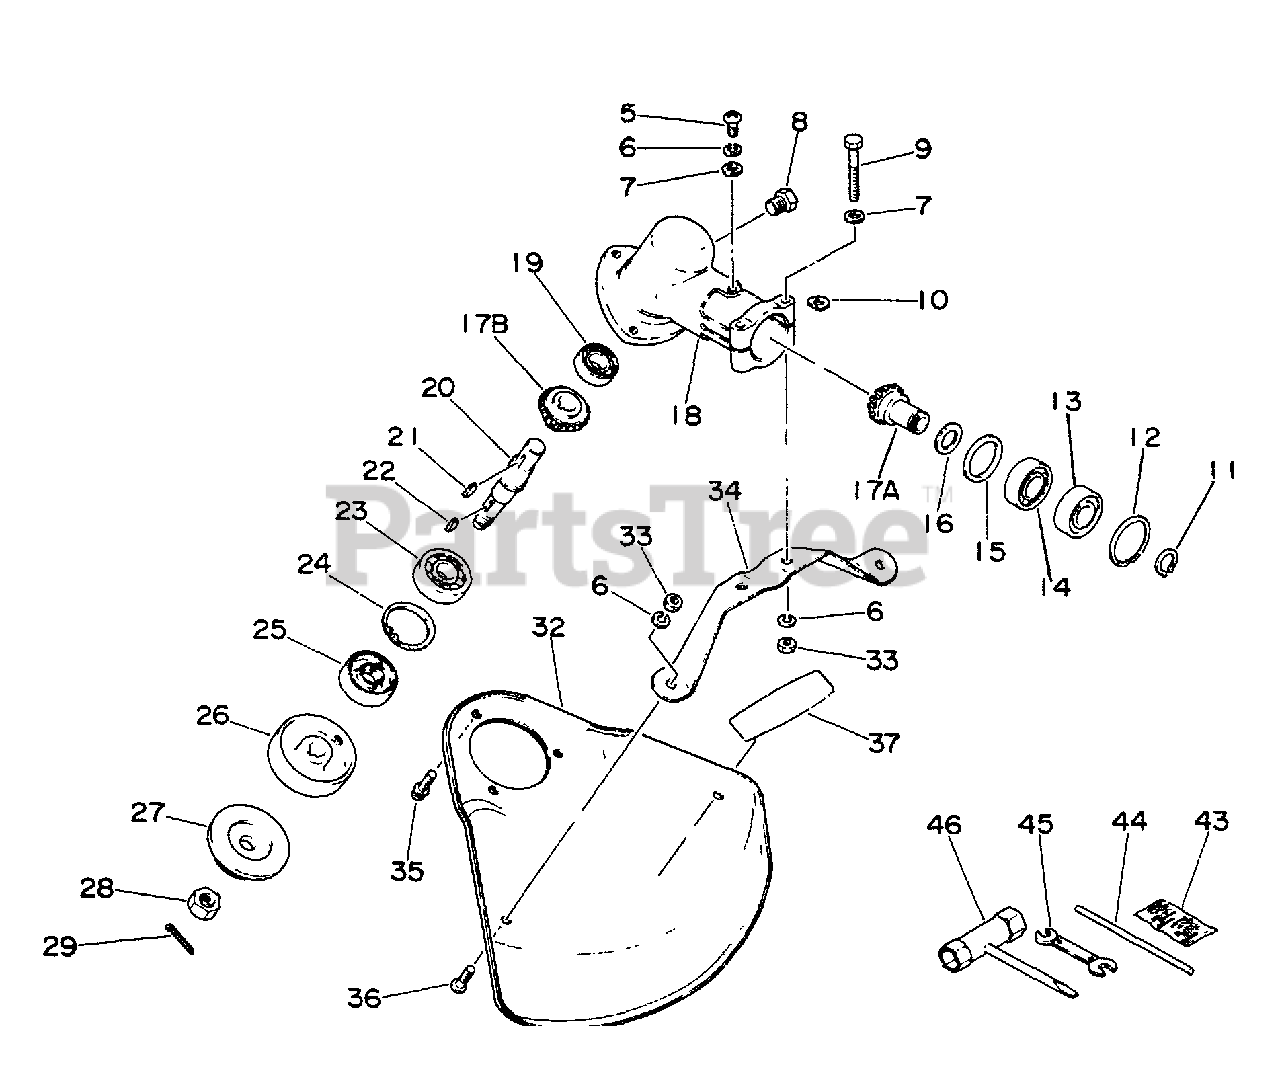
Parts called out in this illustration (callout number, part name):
5	SCREW - 5X10
6	LOCKWASHER - 5
7	WASHER - 5
8	BOLT - 8X8
9	BOLT - 5X40
11	RING, RETAINING - 12
12	RING, RETAINING - 28
13	BEARING, BALL - 6001
14	BEARING, BALL - 6001
18	CASE, GEAR
19	BEARING, BALL - 6000
20	DRIVESHAFT
23	BEARING, BALL - 6201
24	RING, RETAINING - 32
25	SEAL, OIL
26	ADAPTOR, BLADE - UPPER
27	ADAPTOR, BLADE - LOWER
28	NUT - 10 -- LEFT HAND
29	PIN, SPLIT - 2X22
32	SHIELD
34	BRACKET, SHIELD
35	SCREW - 5X10
36	SCREW - 5X8
37	LABEL - ECHO
43	PIN, SPLIT - 2X22
44	LOCKING TOOL
45	SPANNER - 8X10mm
46	T-WRENCH
